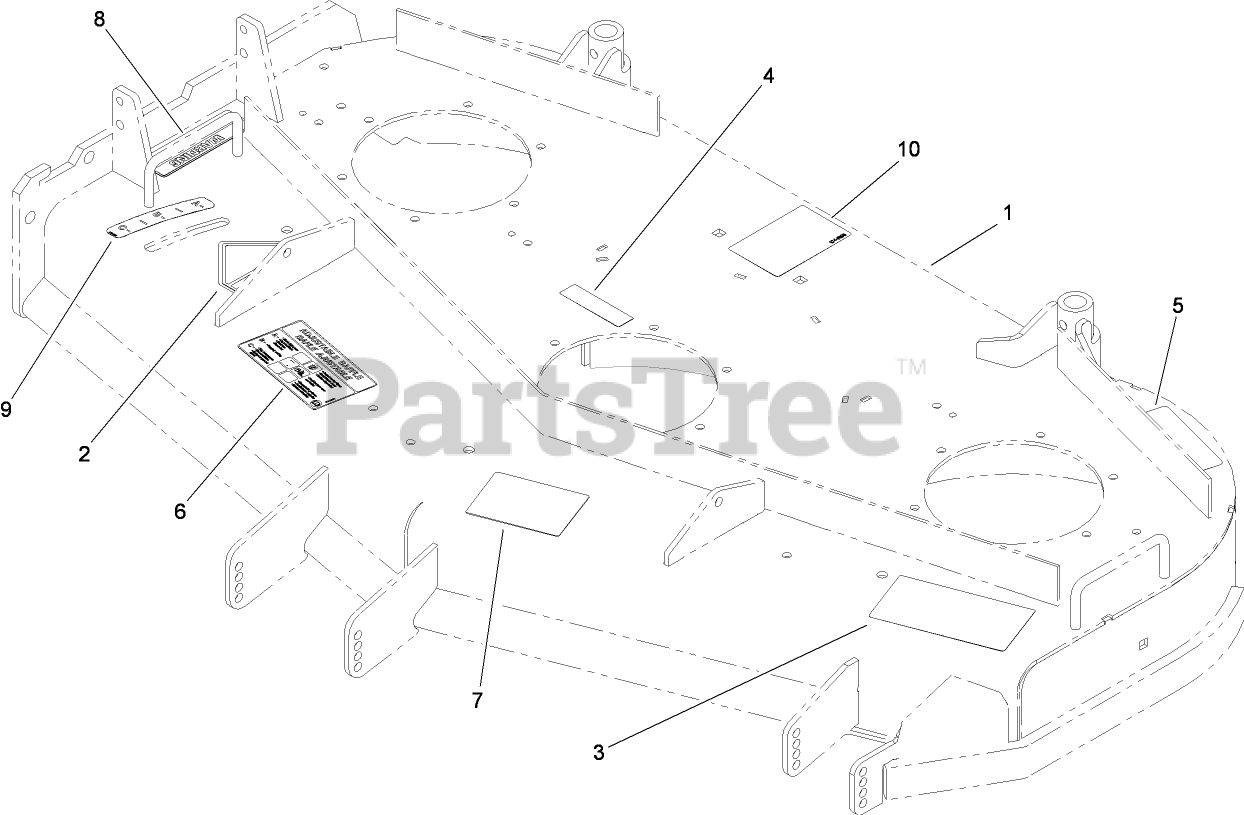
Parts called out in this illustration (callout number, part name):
1	48 INCH DECK ASM
2	DECAL-DANGER
3	DECAL-DANGER, THROWN OBJECT
4	DECAL-COVER, MISSING
5	DECAL-TORQUE
6	DECAL-ADJUSTMENT, BAFFLE
7	DECAL-SCALP, ANTI
8	DECAL-WARNING
9	DECAL-SETTING, BAFFLE
10	DECAL-ROUTING, BELT
